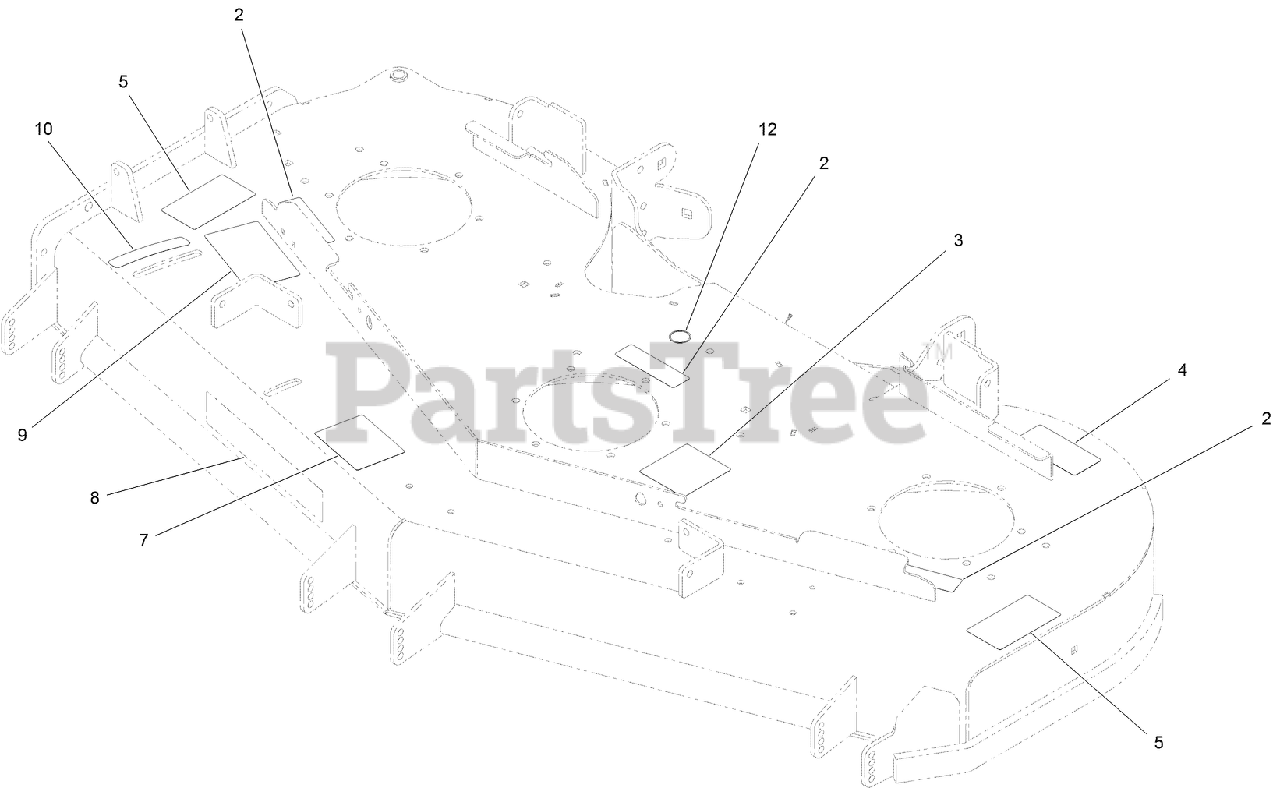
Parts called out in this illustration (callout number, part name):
2	DECAL-COVER, MISSING
3	DECAL-ROUTING, DECK BELT
4	DECAL-TORQUE, BLADE BOLT
5	DECAL-DANGER
7	DECAL-SCALP, ANTI
9	DECAL-ADJUSTMENT, BAFFLE
10	DECAL-SETTING, BAFFLE
12	DECAL-GREASE
